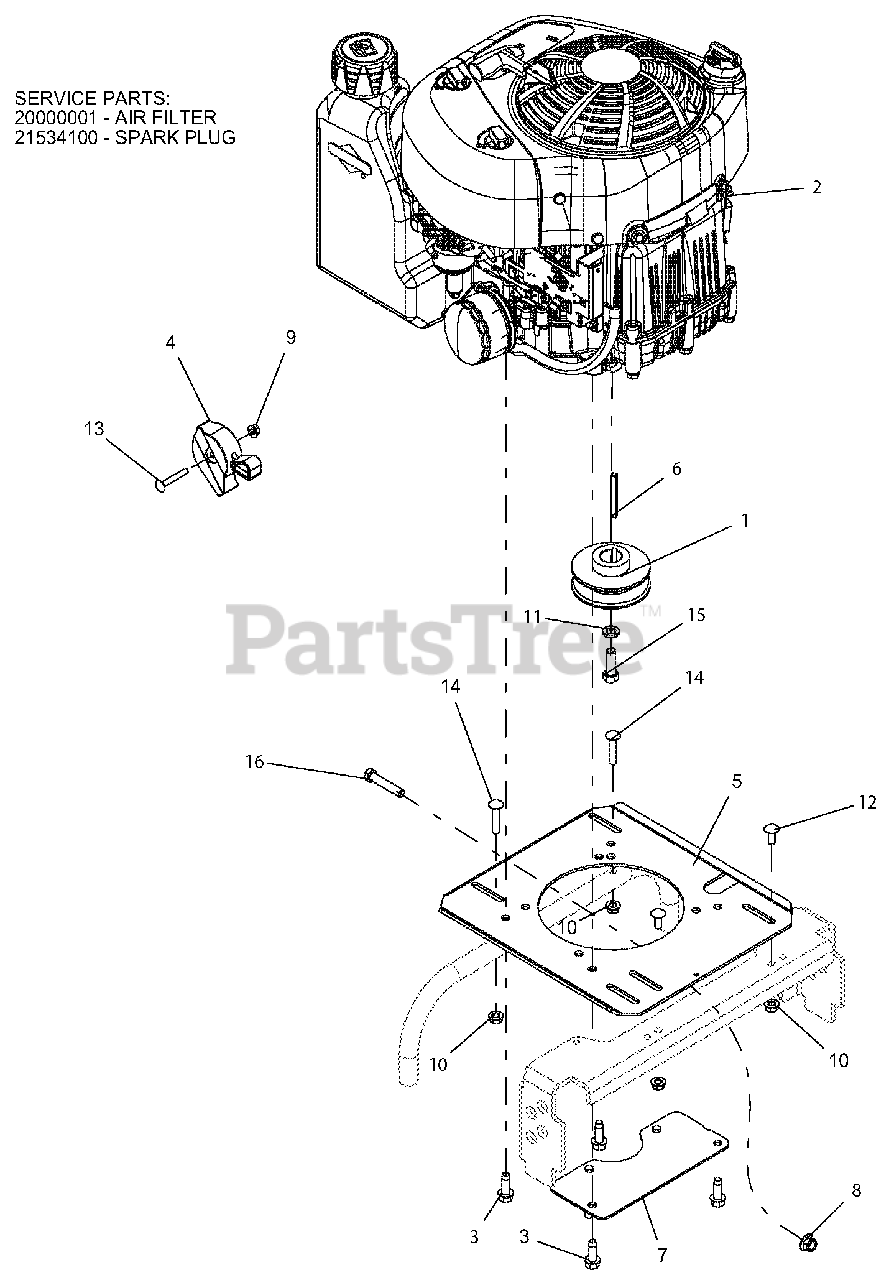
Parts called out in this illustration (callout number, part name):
1	WMT-SHEAVE, ENGINE HWM INTEK
2	ENGINE, BRIGGS -10.5HP INTEK CARB
2	AIR FILTER
2	SPARK PLUG
3	SCR-TAP .38-16X1.00 HWH TR YZ
4	CABLE, THROTTLE , KILL & CHOKE
5	PLATE, ENGINE (RED)
6	KEY, .25X.25X2.25
7	WLDMT, HWM ENGINE BELT FINGER (BLACK)
8	NUT-LK-NYL-FLG .38-16 YWZC
9	NUT, LK-TOP-FLG .25-20 YWZC
10	NUT, LK-TOP-FLG .312-18 YWZC
11	WSHR-LK .44X.109 REG YWZC
12	BLT-RHDSSQNK .31-18X.75 G5YZ
13	BLT-RDHDSQNK .25-20X1.75 G5 Y
14	BLT-RDHDSQNK .31-18X1.50 G5 YWZC
15	BLT, HEX .44-20X1.25 GR5 YWZC
16	BLT-HEX .38-16X2.00 FTH GR5 YWZC
